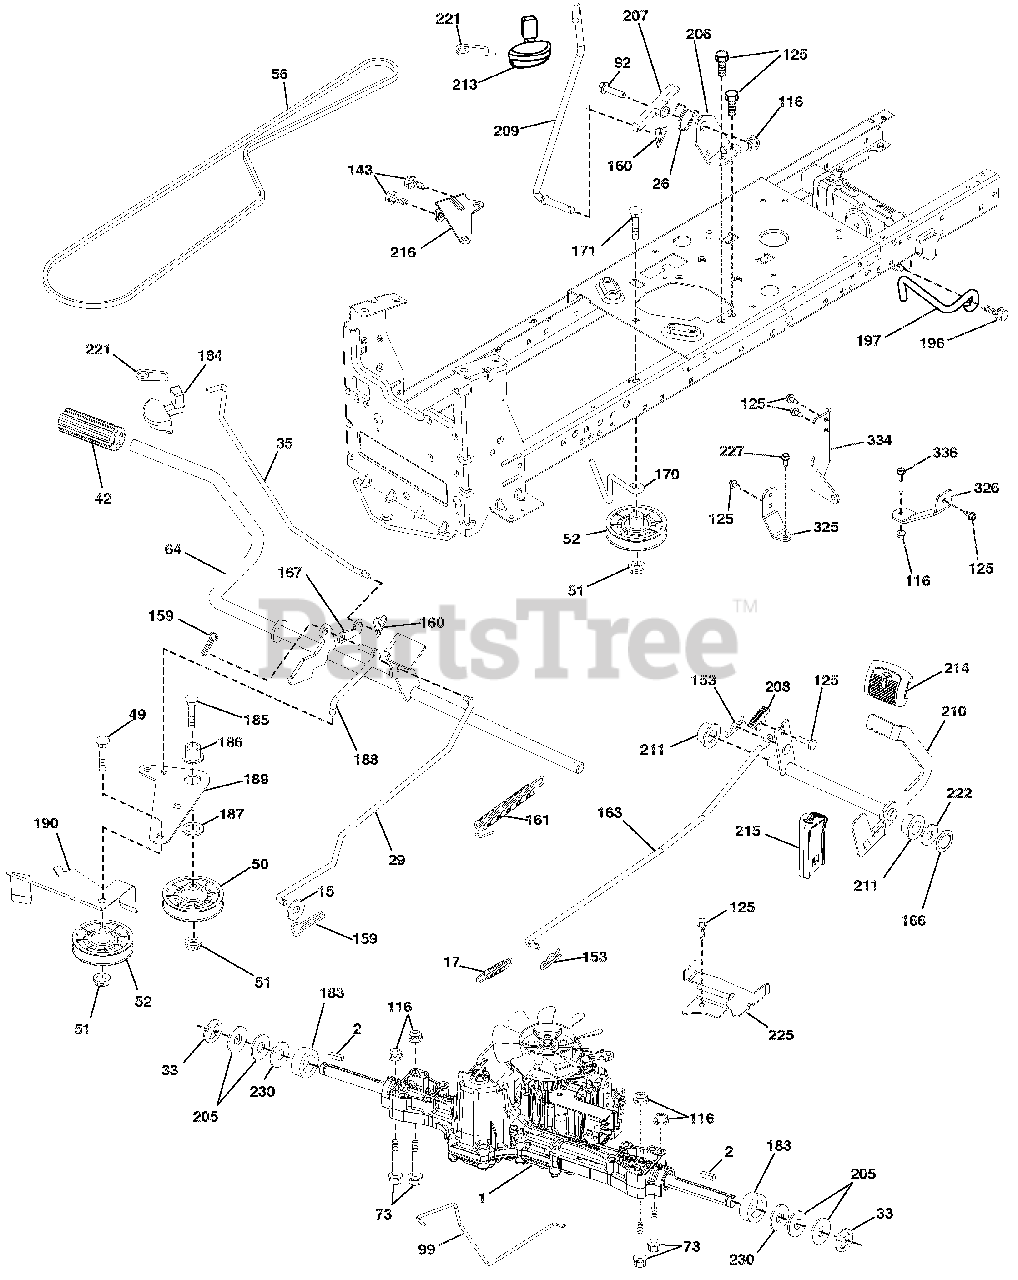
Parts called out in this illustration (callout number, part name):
1	(ORDER PARTS FROM TRANSAXLE
1	MANUFACTURER.)
2	KEY.SQUARE.2.0 X .1845/.1865
15	WASHER.13/32 X 13/16 X 16 GA.
17	SPRING.BRAKE.K46.GREEN
26	SPRING.RETURN.CRUISE
29	ROD.BRAKE.K46
33	E-RING.#5133-75
35	ROD.BRAKE.PARKING.LT.TEX
42	COVER PEDAL BLK ROUND
49	BOLT.RDHD.3/8-16UNCX1-3/4.GR5
50	IDLER.FLAT.910"OFFSET
51	Nut, Hex, Flangelock 3/8-16
52	IDLER.V-GROOVE.910"OFFSET
56	V-BELT.MOWER.92.40.42/K46
64	SHAFT ASM.PEDAL.BRK.CNTRL.PCH
73	BOLT.HEX.FLGHD.5/16-18.GR.5
92	Bolt, Hex Head 5/16-18 x 1-1/4
99	ROD BYPASS
116	Nut, Lock Hex Flange 5/16-18 u
125	SCREW.5/16-18X3/4.SMGML.TAP/BL
143	SCREW.THDROL.5/16-18 X 1/2TYTT
153	RETAINER SPRING
159	PIN.COTTER.1/8 X 3/4.CAD.
160	RETAINER.CLIP(M).DIA.290
161	SPRING.RETURN.CLUTCH.6.75
163	ROD CONTROL
166	NUT PUSH .625
167	LATCH.BRAKE.PARKING
170	KEEPER BELT CENTERSPAN
171	BOLT.RD.HD.SQ.NK.3/8-16UNC X 2
183	SPACER.AXLE.HYDRO/PEERLES
184	HANDLE.PARK.BRAKE
185	BOLT.RDHD.3/8-16UNC X2-3/4 GR5
186	SPACER.RETAINER
187	WASHER.13/32 X 2 X 10 GA.
188	LINK.CLUTCH.GROUND DRIVE
189	BELLCRANK.GROUNDRIVE.NSTG/NSTL
190	KEEPER.BELLCRANK.DRIVE.GROUND
196	SCREW.3/8-16X1.SMGML.TAP/R.BLK
197	LINK CLUTCH ANTI-ROTATION
205	WASHER.25/32 X 1-5/8 X 16GA.
206	BRACKET MOUNT LATCH CRUISE
207	LATCH.CONTROL.CRUISE
208	GEAR SECTOR.CONTROL.CRUISE
209	ROD.CONTROL.CRUISE
210	ROCKER ASM.PEDAL CONTROL.TEXLT
211	BEARING.NYLON.BLK..629 ID.
213	KNOB.CONTROL.CRUISE
214	PAD PEDAL FORWARD
215	PEDAL REVERSE
216	BRACKET.PULLEY.IDLER.WTEX
221	RETAINER.SPRING.CLIP.HANDLE
222	WASHER.21/32X1-1/4.10GA.N/PLTD
225	KEEPER.BELT.TRANSAXLE.K46
227	SCREW 5/16-18 X 3/4
230	WASHER.HARDEN..793 X 1.637X060
325	BRACKET
326	BRACKET
334	BRACKET
